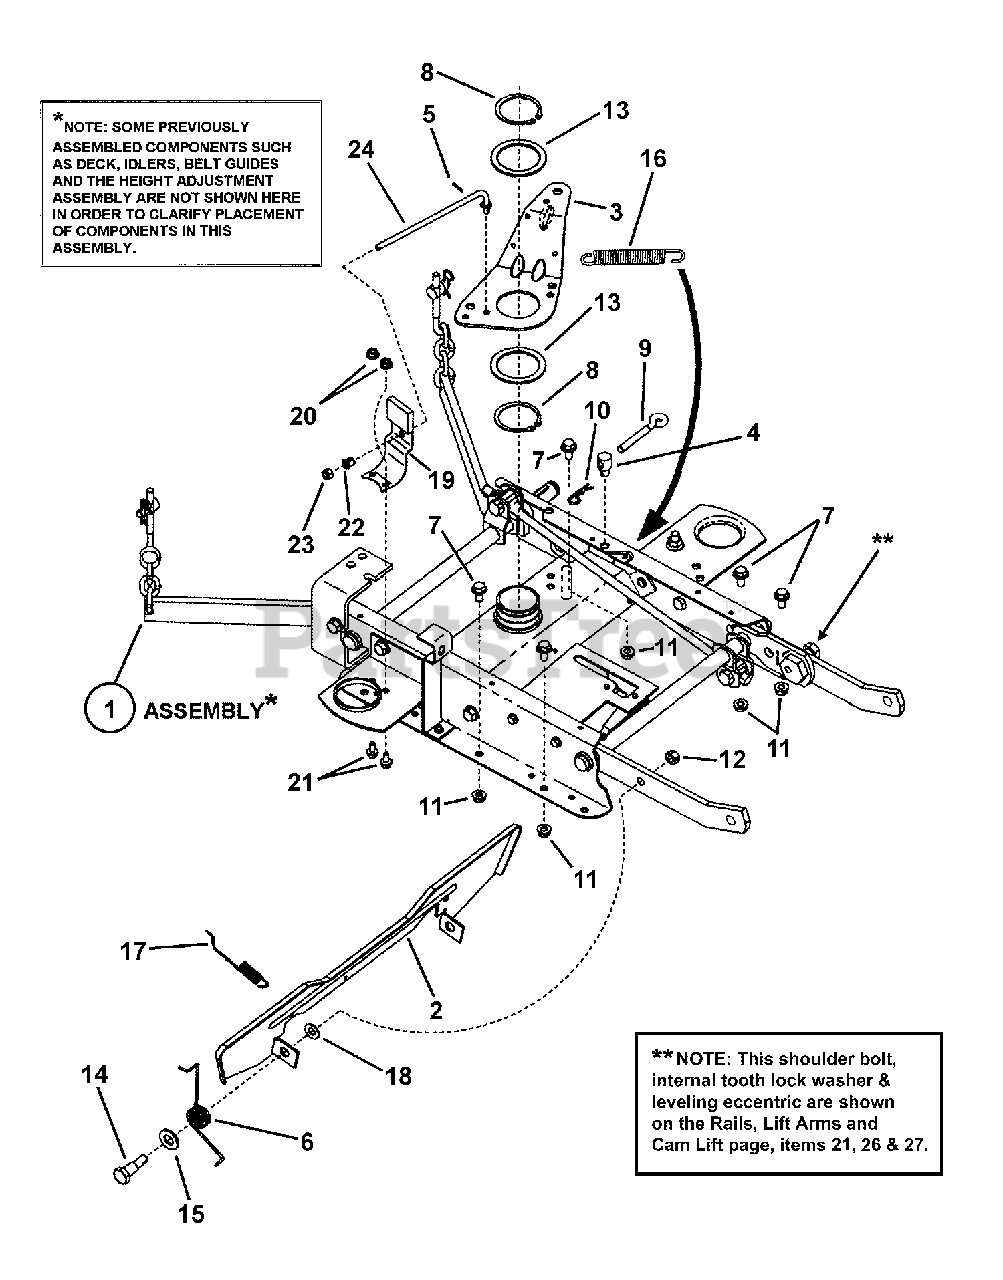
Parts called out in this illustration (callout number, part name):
1	ASSEMBLY, Rail
2	FOOT PEDAL, Blade Stop Control
3	IDLER ARM
4	SWIVEL, Adjustment (with 5/16-18 internal thread)
5	PIN, 1/16 x 1/2" Cotter
6	SPRING, Pedal
7	BOLT, 5/16-18 x 5/8" Hex Flange Lock
8	RING, 2" External Retaining
9	EYE-BOLT, 5/16-18 x 3"
10	HAIR PIN, 3/32 x 1-1/2"
11	NUT, 5/16-18 Hex Flange Lock, GR 5
12	NUT, 3/8-24 Hex Center Lock
13	WASHER, Nylon
14	SHOULDER BOLT, 3/8-24 x 9/16"
15	WASHER, 1/2" Flat SAE
16	SPRING, Return
17	SPRING, .072 Dia. Latch
18	WASHER, 3/8" SAE Flat
19	BRAKE PAD, Spring
20	NUT 1/4-20 Hex Flange Lock
21	BOLT,1/4-20 x 1/2" Hex Flange Lock
22	BUSHING, 3/8" Nylon Snap
23	NUT,1/4-20 Hex Nyloc
24	LINK, Spindle Brake (1/4-20 thread)
